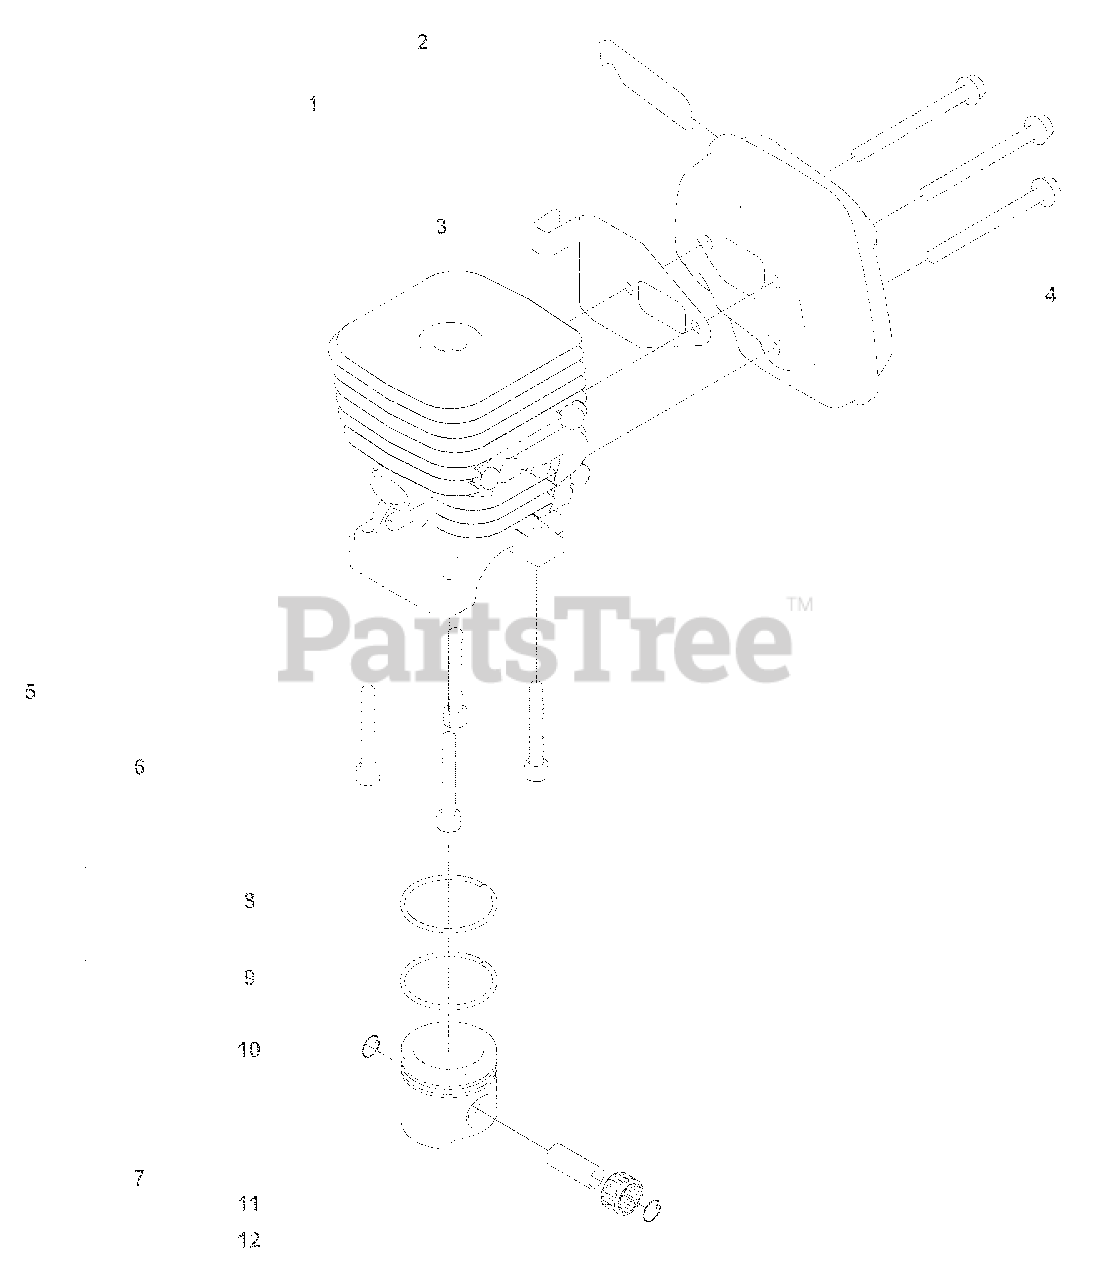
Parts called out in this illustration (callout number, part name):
1	Muffler Kit
2	Spark Arrestor Screen
4	Screw, Ehhfm
5	Cylinder, Complete
6	Screw, Ihscfm M5 X 35 10.9 ZP
8	Piston Ring
9	Piston Ring
